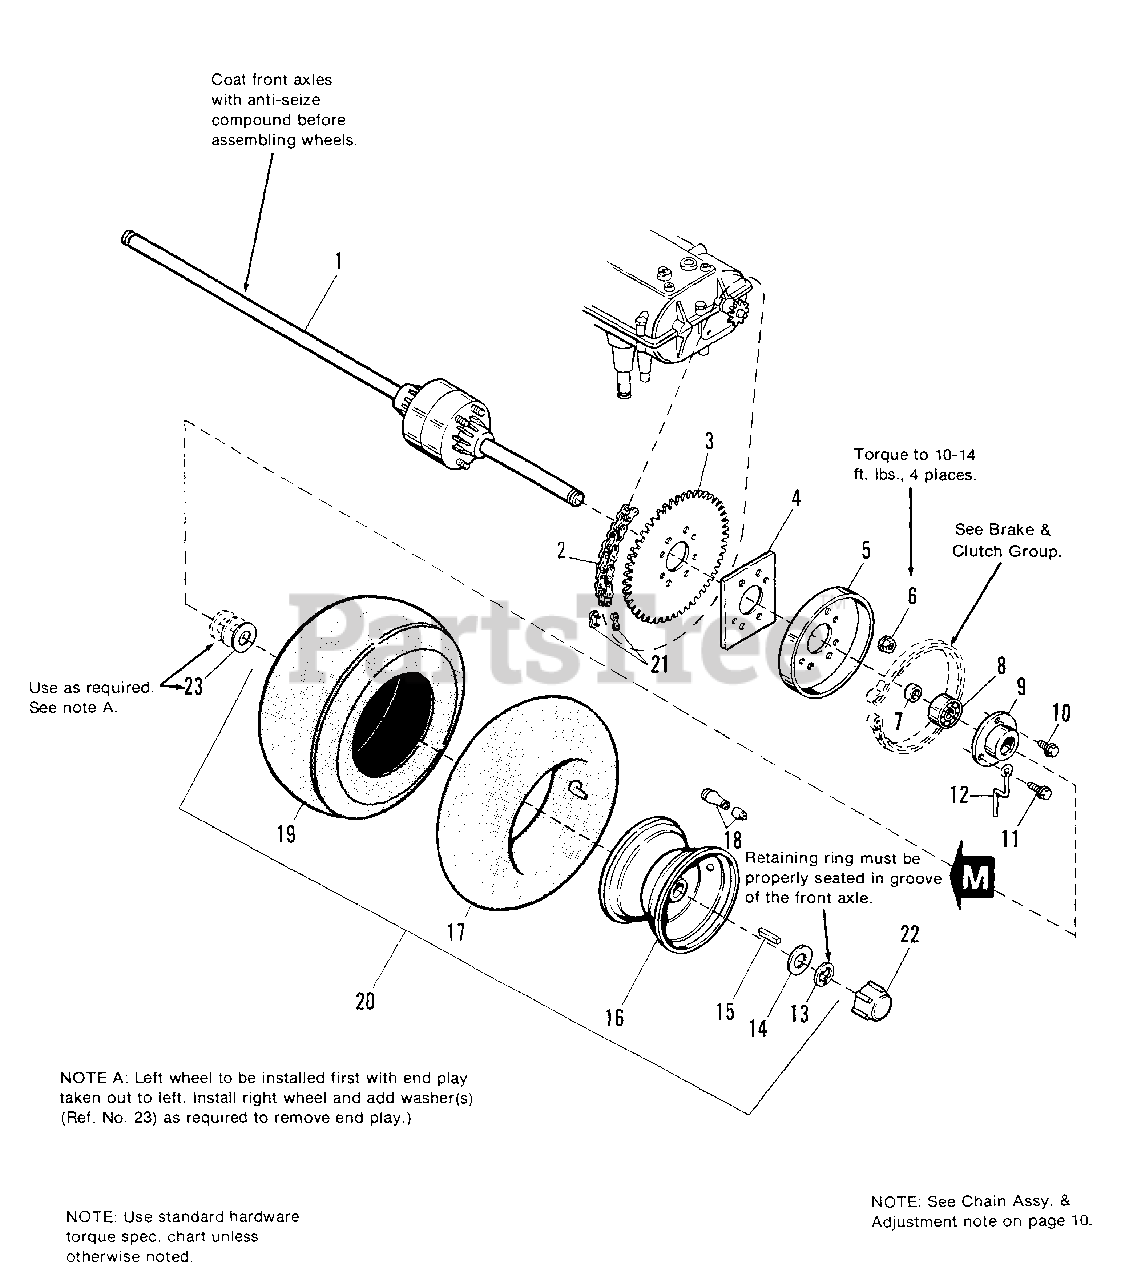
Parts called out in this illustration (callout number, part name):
1	AXLE ASSY., Differential
2	CHAIN, Roller, #41
3	SPROCKET, 54 Tooth
4	SHIM, Sprocket
5	DRUM, Brake
6	NUT, Flange Lock, 5/16-18
7	SPACER, Axle
9	FLANGE, Bearing
10	SCREW, Taptite, 5/16-18 x 1/2
11	SCREW, Taptite, 5/16-18 x 3/4
12	STOP, Brake Band
13	RING, Retaining, Wheel
14	WASHER, 3/4
15	KEY, 3/16 x 3/16 x 1-1/2
16	WHEEL ASSY.
17	TUBE (Service Only)(See note below.)
18	VALVE STEM & CAP
19	TIRE, 15 x 6.00-6
20	WHEEL & TIRE ASSY., 15 x 6.00-6
21	MASTER LINK, Chain #41
22	CAP, Threaded
23	WASHER, Shim, 3/4 x 1-1/16 (Use as needed)
